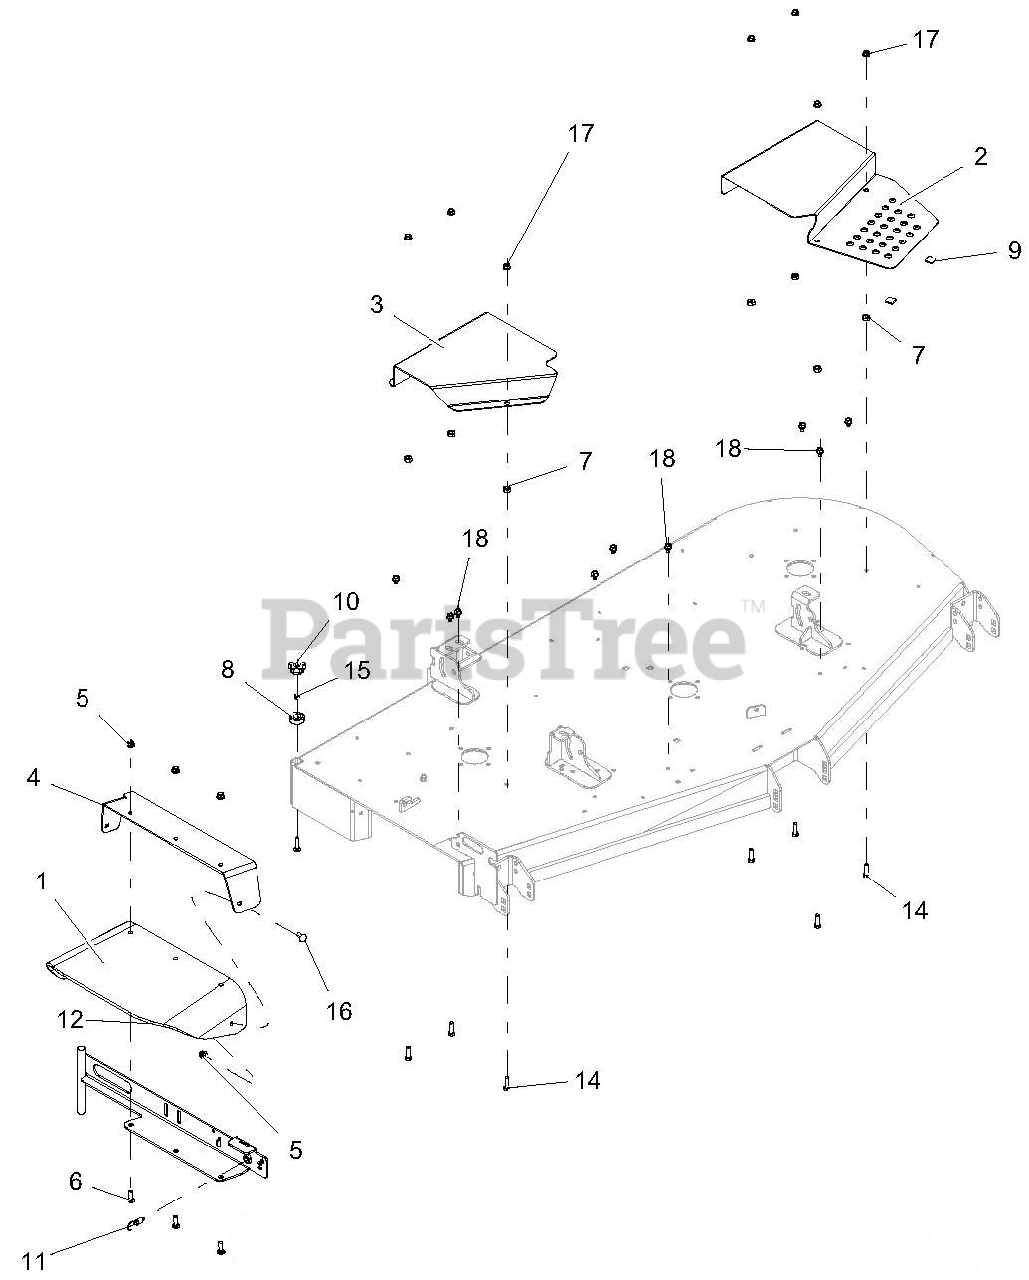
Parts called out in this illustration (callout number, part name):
1	CHUTE, RUBBER DISCHARGE
2	GUARD, 72" LH DECK BELT-RED
3	GUARD, 72" RH DECK BELT-RED
4	SUPPORT, CHUTE MOUNTING BRACKET-RED
5	NUT-LK-NYL-FLG .38-16 YWZC
6	BLT-RDHDSQNK .38-16X1.25 G5 YWZC
7	NUT-HEAVY HEX .38-16 YWZC
8	BUMPER, RECESSED 1.50 X .63 W/.31 HOLE
10	KNOB, CLAMPING
11	PULL PIN,.50-13THDX.310 PLNGR
12	WLDMT, 66"-72" DISCH CHUTE MTG-RED
14	BLT-HEX .38-16X1.25 GR5 YWZC
15	NUT-LK-CTR .31-18 YWZC
16	BLT-RDHDSQNK .38-16X1.00 G5 YWZC
17	@NUT-SPNLK-FLG .375-16 YWZC
18	SCR-TAP .38-16X.50 HWH TR YWZ
